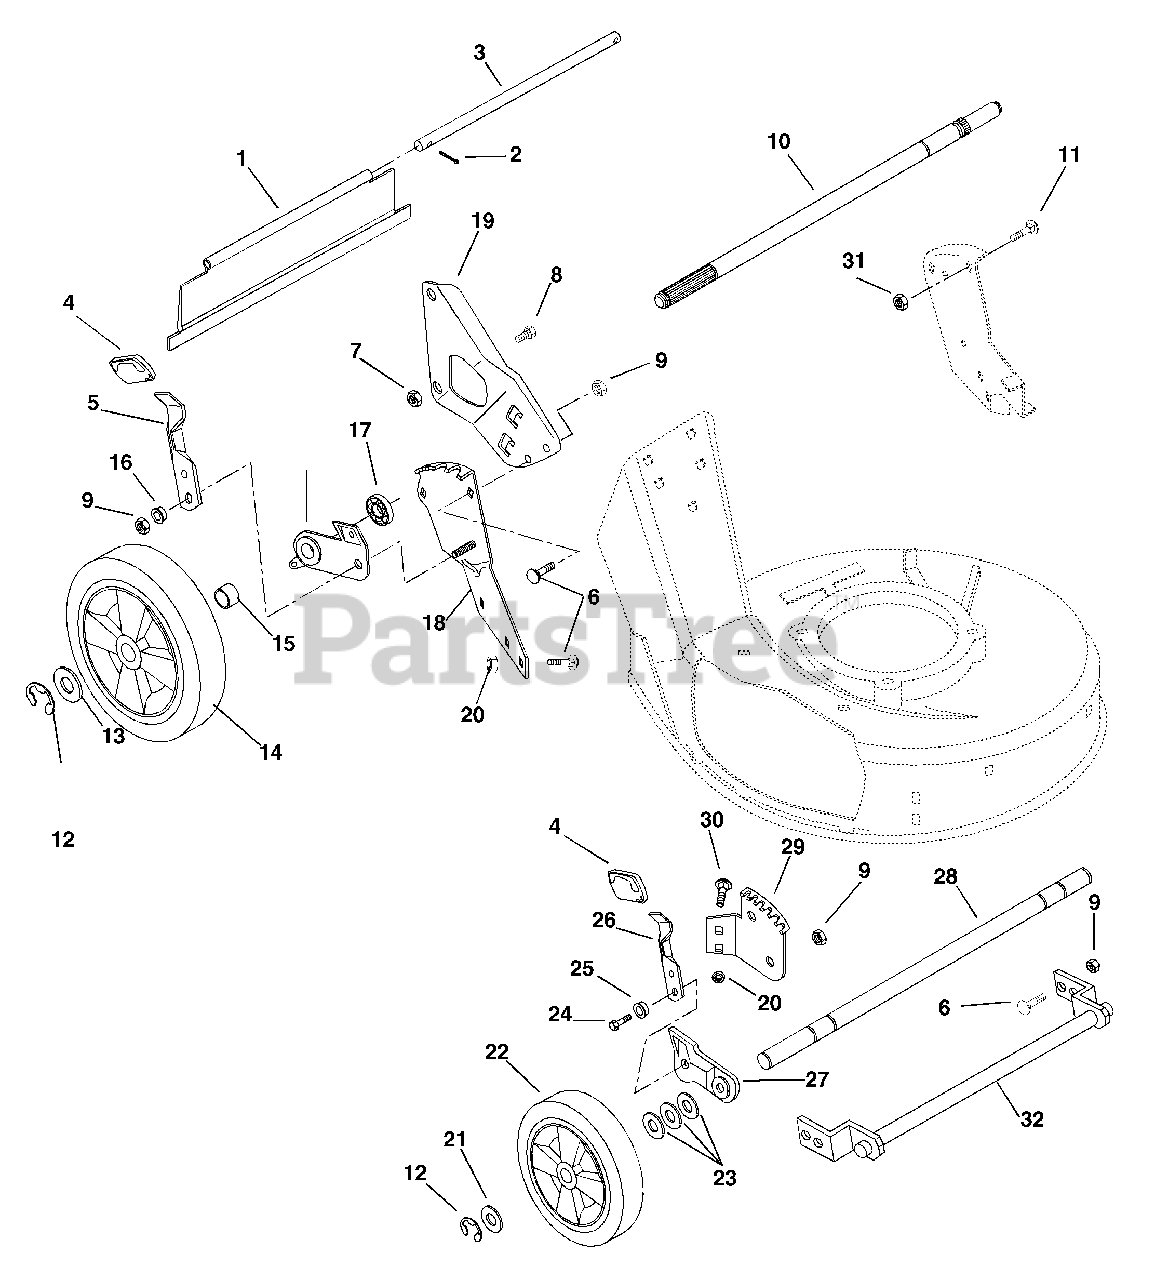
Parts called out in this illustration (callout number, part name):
1	REAR PROTECTIVE GUARD, S.P.
1	REAR PROTECTIVE GUARD, PUSH
2	@PIN-CTR .06X.50 EXTPRSQCT YWZ
3	ROD
5	HEIGHT ADJUSTMENT LEVER
6	@BLT-RHDSSQNK .31-18X.62 G5YZ
7	@NUT-LK-CTR .38-16 YWZC
8	HANDLEBAR STUD
9	@NUT-LK-CTR .31-18 YWZC
10	REAR AXLE,5/8 DIA
10	REAR AXLE-PUSH MOWER MM
10	REAR AXLE-PUSH MOWER
11	BLT-RDHDSQNK .31-18X1.0 SHTYZ
12	RG-RTNG-EXT .500X.042 (E)
13	WSHR-FL-STL .505X.880X.072 YWZ
14	WHL, LH 10.50"
14	WHL, RH 10.50"
14	10 1/2 TIRE SKIN
14	TIRE, REAR 10X1.75 #6 GRAY
15	SPACER TUBE, SELF PROPEL
15	SPACER TUBE,PUSH LH
15	SPACER TUBE PUSH RH
16	BSHG-FLG .32X.500X.344X.880
16	R.H. REAR ADJUSTOR BRACKET
16	L.H. REAR ADJUSTOR BRACKET
16	REAR ADJUSTMENT BRACKET L.H.
16	REAR BRACKET & BEARING ASSY RH
16	REAR BRACKET & BEARING ASSEMBL
17	BRG-BALL .625X1.383X.50
18	QUADRANT, REAR LH
18	QUADRANT, REAR RH
19	RH HANDLEBAR MTG. BRKT
19	LH HANDLEBAR MTG. BRKT
19	RH HANDLEBAR MOUNT WELDMENT
19	LH HANDLEBAR MOUNT WELDMENT
20	@NUT-SPNLK-FLG .312-18 YWZC
21	WSHR-FL-STL .505X.880X.072 YWZ
22	WHL 7.50" .50 BORE, 1.50 HUB
22	TIRE, FRONT 7X1.50
23	WSHR-FL-STL .52X.827X.062 YWZC
24	@BLT-HEX .31-18X1.00 GR5 YWZC
25	BSHG-FLG .32X.500X.344X.880
26	FRONT HEIGHT ADJUSTMENT LEVER
27	LEFT ADJUSTOR BRACKET ASSEMBLY
27	RIGHT ADJUSTOR BRACKET ASSEMBL
27	RH ADJUSTER BRACKET
27	LH ADJUSTER BRACKET
28	FRONT AXLE
29	FRONT QUADRANT, LH
29	FRONT QUADRANT, RH
30	@BLT-RDHDSQNK .31-18X.50 G5YZ
31	@NUT-LK-NYL .312-18 YWZC
32	DETHATCHER RETAINER WELDMENT
